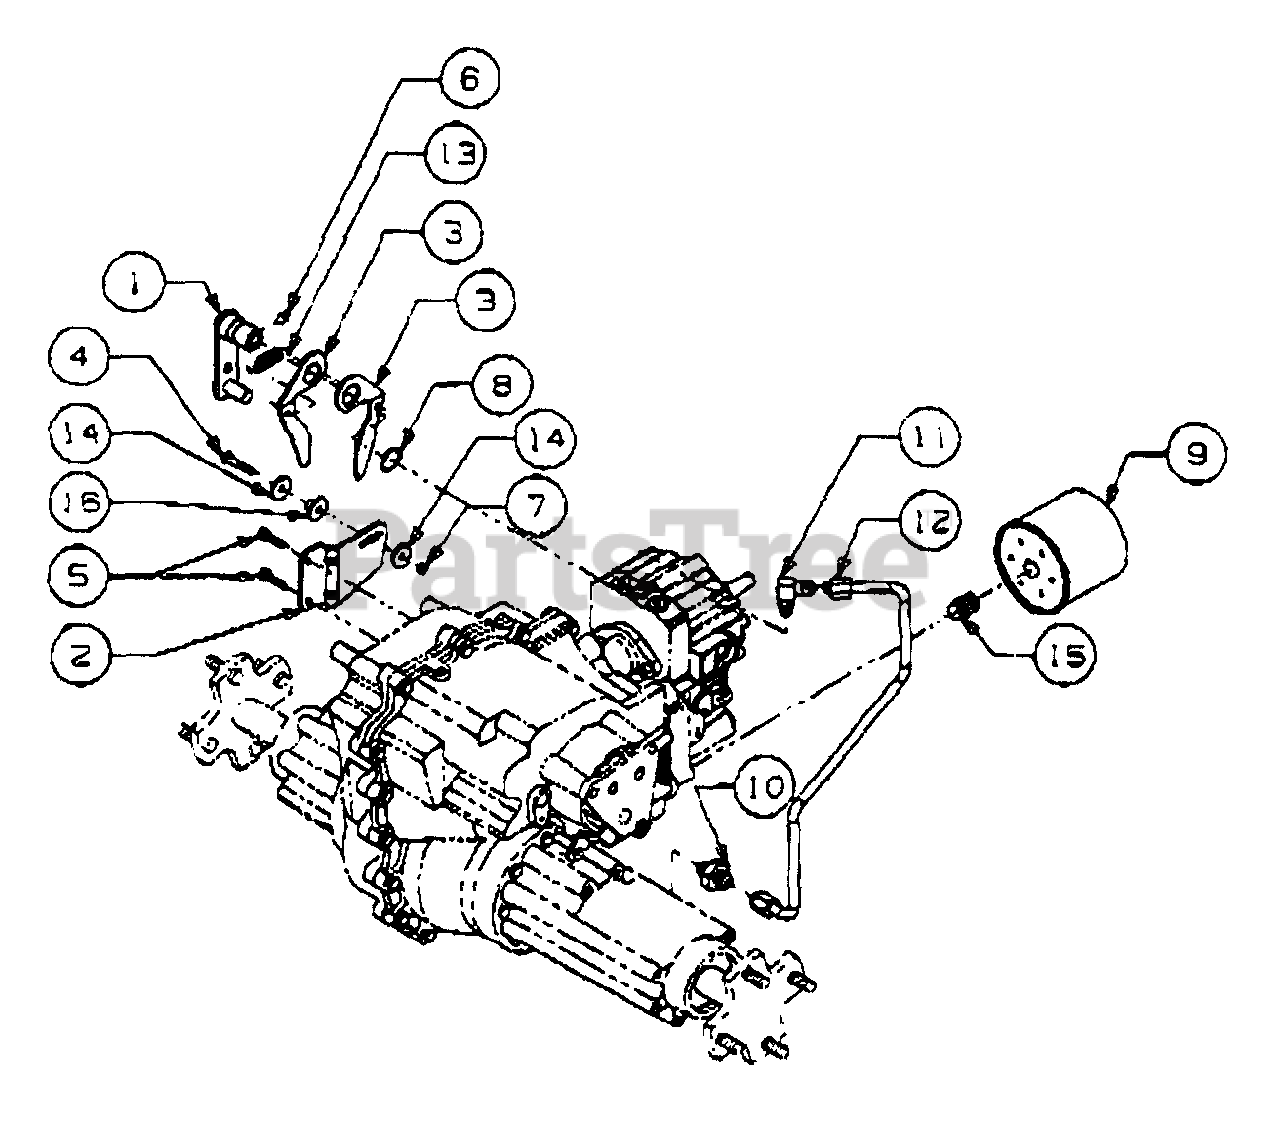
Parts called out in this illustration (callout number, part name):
1	Arm Assy, Control
2	Bracket, Hydro Neutral
3	Arm, Neutral
4	Screw, Hex Cap, 1/4-20 x 1.25 Lg
5	Screw, Hex Wash TT-Tap, 1/4-20 x 1.0 Lg
6	Screw Patch, Set
7	Nut, Hex Top Lock 1/4-20
8	Ring, Snap, .875 Shaft
9	Filter, Oil
10	Connector, Tube 37 Deg. w/O-Ring
11	Elbow, Adjustable w/O-Ring
12	Tube, Pickup
13	Spring, Extension, .5O OD x 1.97 Lg
14	Washer, Flat .25 x .93 x .120 Thk
15	Nipple, Oil Filter
16	Spacer, Centering
